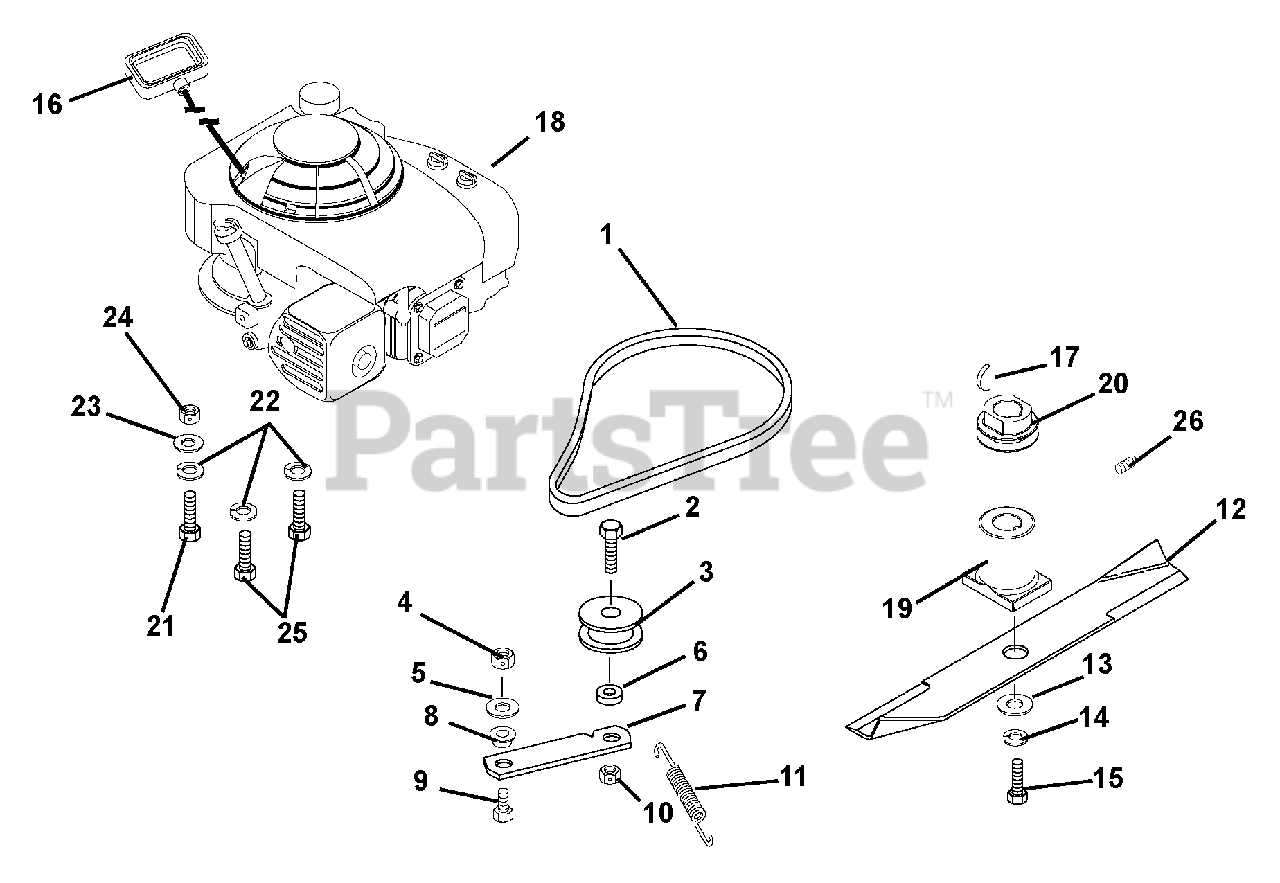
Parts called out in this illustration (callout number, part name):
1	V-BELT, 3L-COGGED
2	BLT-HEX .44-14X1.50 GR5 YWZC
3	IDLER-FLAT 1.75 X .47
4	NUT-LK-CTR .31-18 YWZC
5	WSHR-FL-STL.344X.688X.065YWZC
6	BSHG-SLV .469 X .750 X .430
7	IDLER ARM
8	BSHG-FLG .325X.501X.250X1.120
9	BLT-HEX .31-18X.75 GR5 YWZC
10	NUT-LK-CTR .44-14 YWZC
11	SG-TENS .043X.44X3.31 WLD 5.8
12	21" MOWER BLADE
13	WSHR-FL-STL .390X1.5X.125 YWZC
14	WSHR-LK .38X.094 REG YWZC
15	BLT-HEX .38-24 X 2.00 GR8 YWZC
16	HANDLE, RECOIL START
17	KEY-WDRF .156X.625X.25 SAE 6
18	ENGINE - HONDA 5.5 HP OHV
19	ADAPTER - BLADE HUB
20	PULLEY - UNV DRIVE - STEEL
21	BLT-HEX .31-24X1.50 GR5 YWZC
22	WSHR-LK .31X.078 REG YWZC
23	WSHR-FL-STL.344X.688X.065YWZC
24	NUT-HEX .312-24 YWZC
25	BLT-HEX .31-24X1.00 GR5 YWZC
26	SCR-SET .31-18X.38 SKHCUPDL
